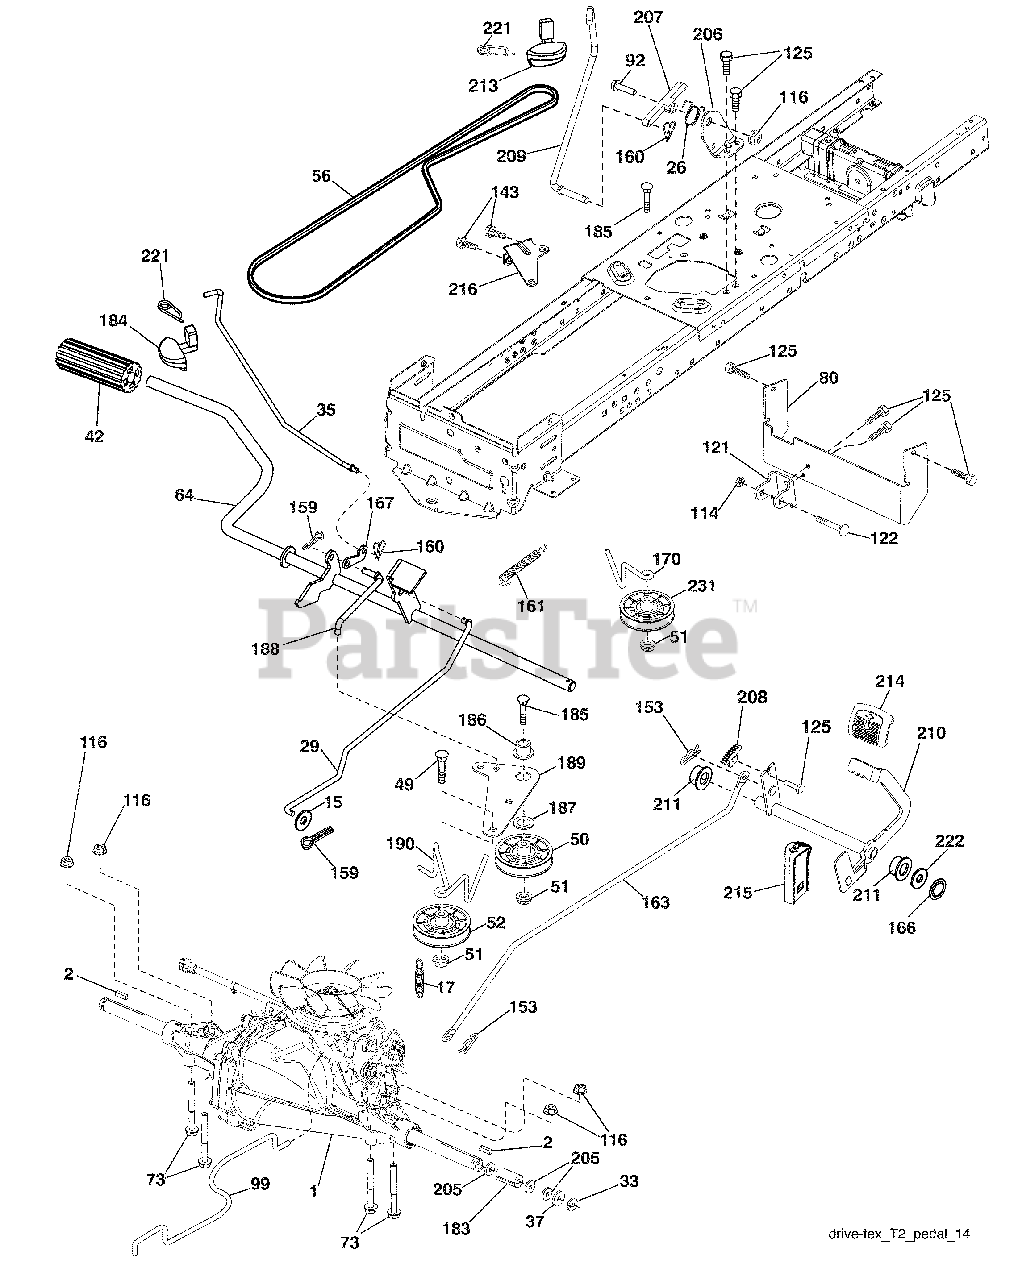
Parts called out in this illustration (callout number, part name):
1	Transaxle, Hydro Gear T2-AABC-1X2B-1GX1(Internal Parts Not Available-Contact-Hydro-Gear-Dist.)
2	Key Square
15	Washer 13/32 x 13/16 x 16 Ga.
17	Spring, Brake
26	Spring Return Cruise
29	Rod, Brake
35	Rod, Brake, Park
37	Washer 25/32 x 1-1/4 x 16 Ga.
42	Cover, Foot Pedal
50	Pulley Idler Flat
51	Lock Nut 3/8-16
52	Idler V-Groove 910" Offset
56	V-Belt, Drive
64	Shaft Asm. Pedal Brake Control
73	Bolt Hex 5/16-18 Gr. 5
80	Strap Torque
92	Bolt Fin Hex 5/16-18 unc x 1.25
99	Rod Spring Bypass
114	Nut Lock HX w/Ins 5/16-18
116	Nut Lock Hex Flange 5/16-18
121	Bracket Strap Torque
122	Bolt 5/16-18 x 2.50
125	Screw 5/16-18 x 3/4
143	Screw Thdrol 5/16-18 x 1/2
153	Retainer Spring 1"
159	Pin Cotter 1/8 x 3/4
160	Retainer Clip
161	Spring, Return, Clutch
163	Rod Control
166	Nut Push
167	Latch Brake Parking
170	Keeper V-Idler
183	Spacer Axle
184	Handle Parking Brake
186	Spacer Retainer
187	Washer
188	Link Clutch Ground Drive
189	Bellcrank Ground Drive
190	Keeper Bellcrank Ground Drive
205	Washer 25/32 x 1-5/8 x 16 Ga.
206	Bracket Mount Latch Cruise
207	Latch Control Cruise
208	Gear Sector Control Cruise
209	Rod Control Cruise
210	Rocker Asm. Pedal Control
211	Bearing Nylon
213	Knob Control Cruise
214	Pedal Forward
215	Pedal Reverse
216	Bracket Pulley Idler
221	Retainer Spring Clip Handle
222	Washer 21/32 x 1-1/4 10 Ga.
231	Idler V-Groove 1.688" Offset
